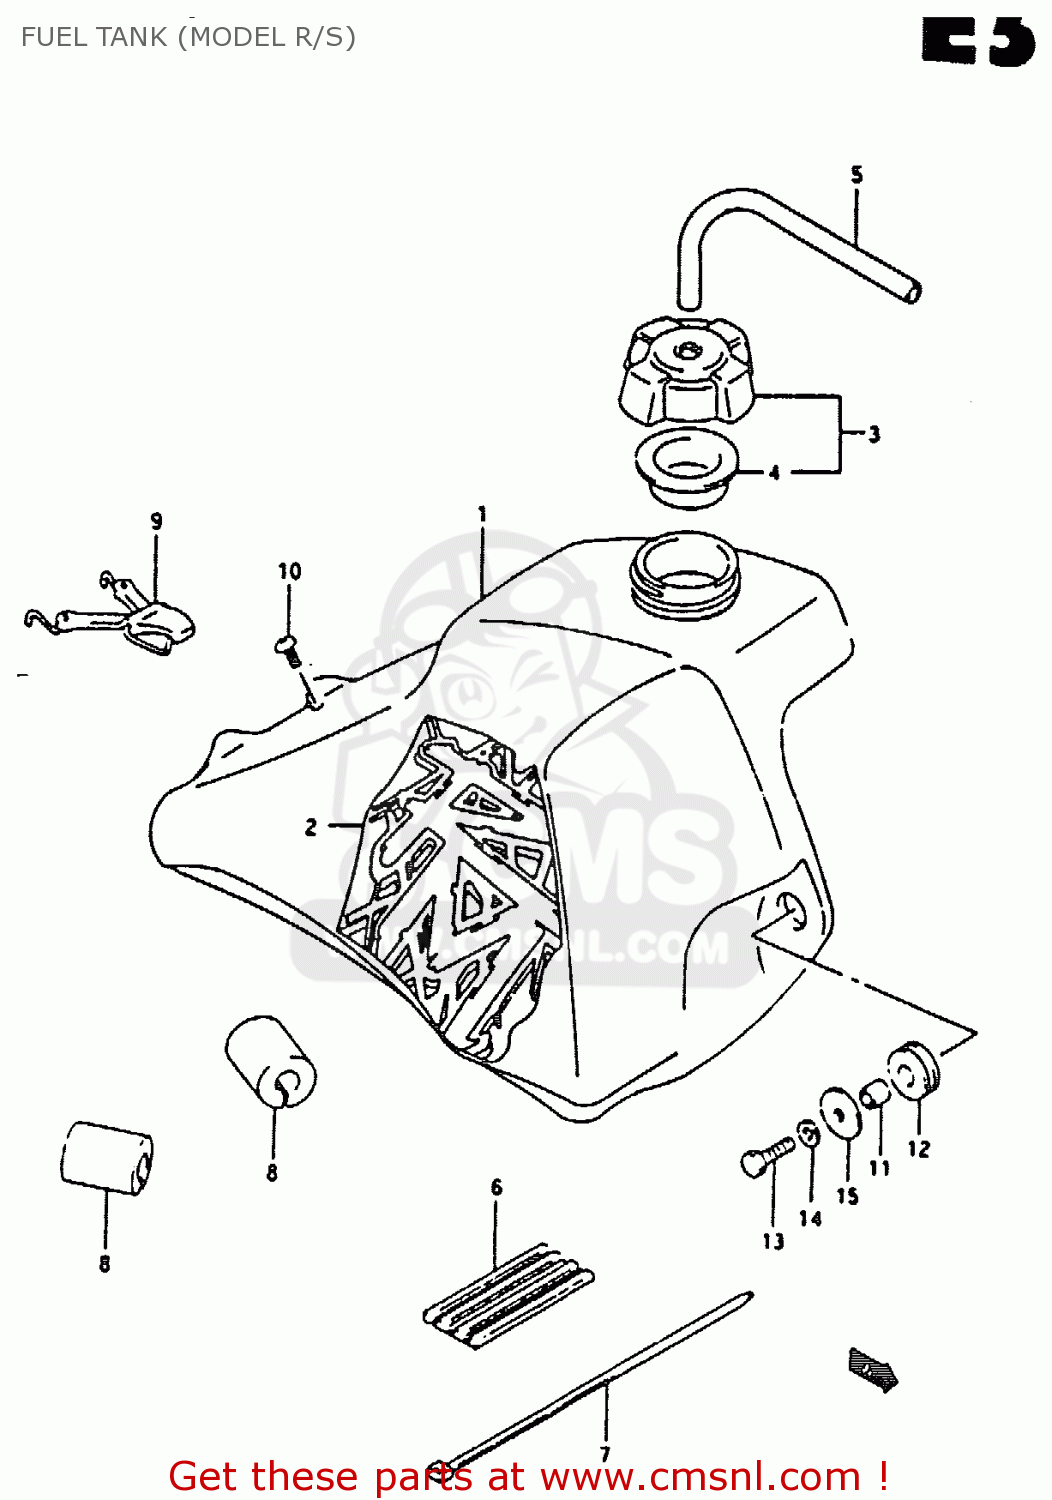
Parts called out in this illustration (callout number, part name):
1	TANK SET,FUEL
2	EMBLEM
3	CAP SET,FUEL TANK
4	GASKET,CAP (NAS)
5	HOSE
6	CUSHION,FUEL TANK UPR FR
7	CLAMP
8	CUSHION,FUEL TANK UPR RR
9	BAND,FUEL TANK RR
10	SCREW
11	SPACER (6.8X10X11.5)
12	CUSHION
13	BOLT
14	WASHER,LOCK
15	WASHER (6.5X24X1.6)
21	LABEL,UNLEADED FUEL
22	LABEL,UNLEADED FUEL
